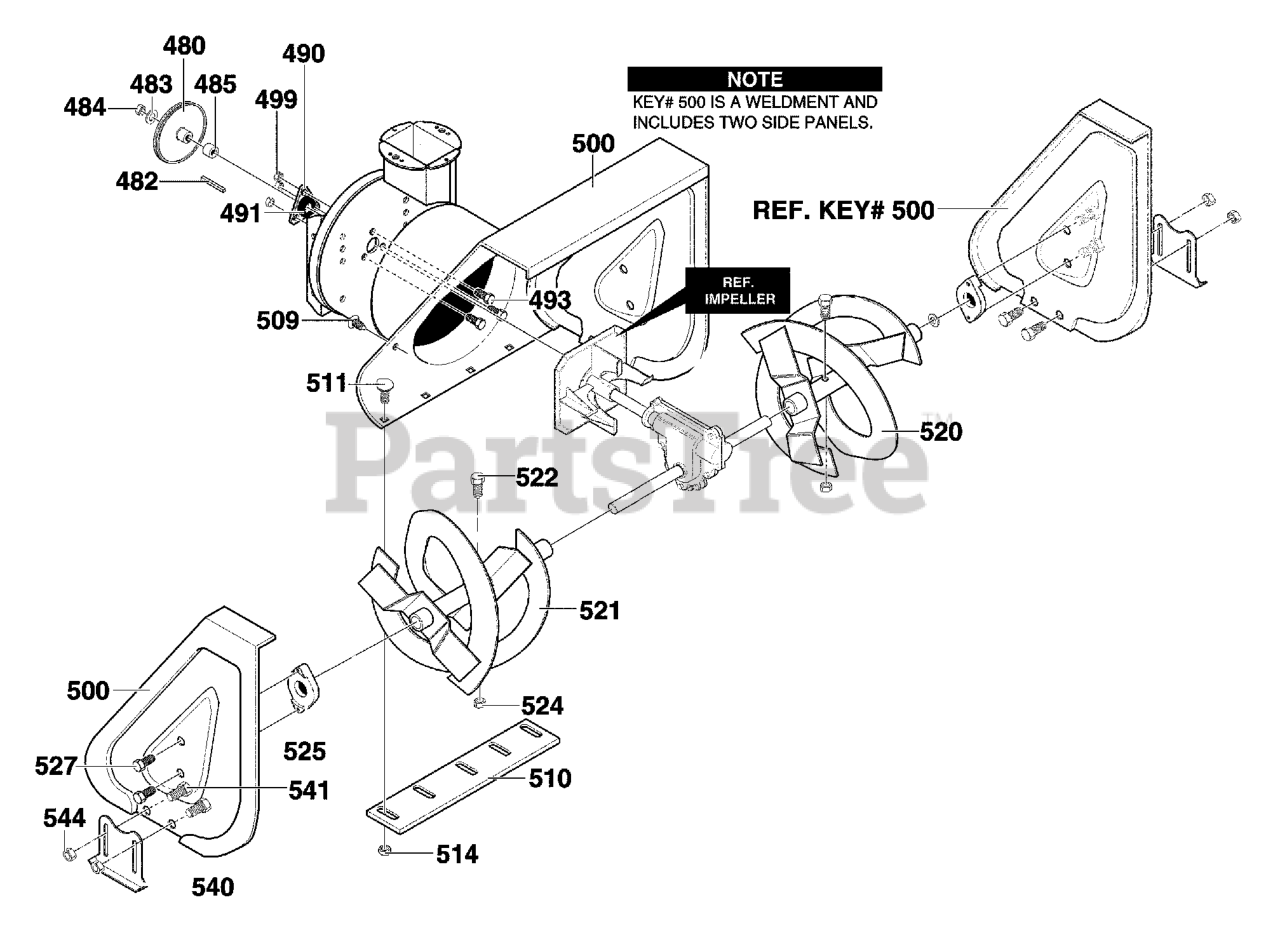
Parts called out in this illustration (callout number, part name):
480	PULLEY, V4L
482	KEY, SQUARE
483	WASHER, FLAT .53X1.00X.063
484	NUT, 1/2-20 REGHEXCTRLK
485	SPACER, SLEEVE
490	RETAINER, BALL
491	BEARING, BALL
493	SCREW, 5/16-18 x 0.75
499	NUT, 5/16-18
500	HOUSING, ASSY
509	PLUG, CHRISTMAS TREE
510	SCRAPER BLADE
511	BOLT, 1/4-20X.75 CARR.
514	NUT, 5/16-18 HEXWDFLLK WHIZ
520	AUGER, LH
521	AUGER, RH
522	BOLT
524	NUT, 5/16-18 REGHXCTRLK
525	BEARING, AUGER SHAFT
527	SCREW, 5/16-18 x 0.75
540	SKID, HEIGHT ADJUST
541	BOLT, 5/16-18X .75
544	NUT, 5/16-18
545	STIFFENER
546	BOLT, 5/16-18
547	FLATWASHER
549	NUT 5/16-18
